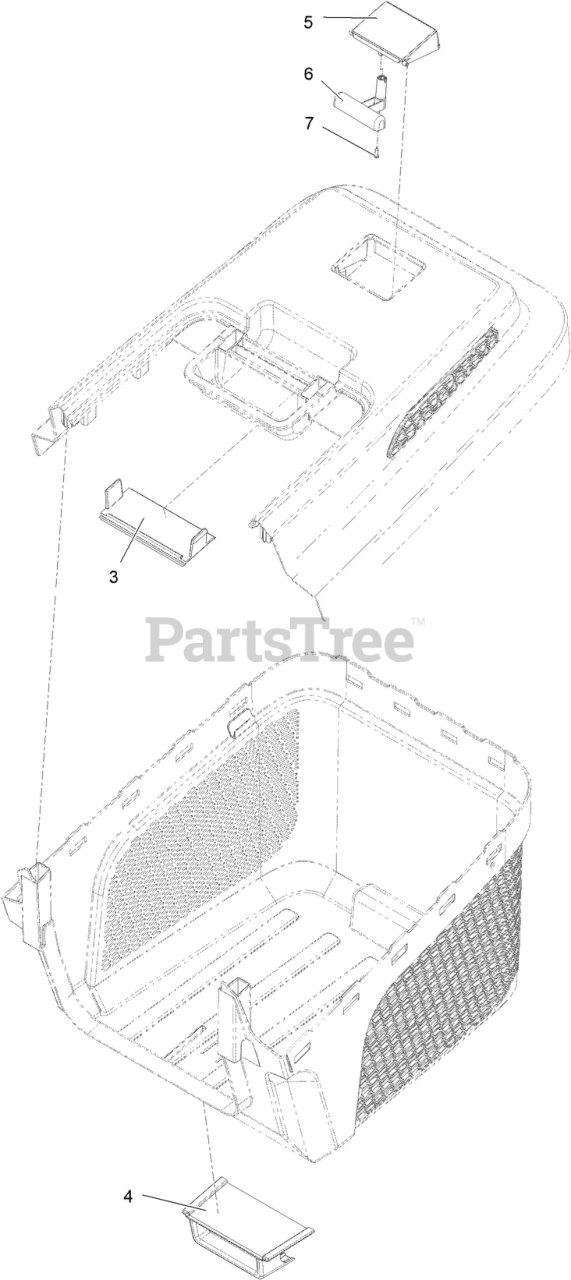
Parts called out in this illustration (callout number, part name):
3	GRASS BOX HANDLE INFILL
4	GRASS BOX HOOK
5	GRASS BOX FULL INDICATOR
6	COUNTER WEIGHT
